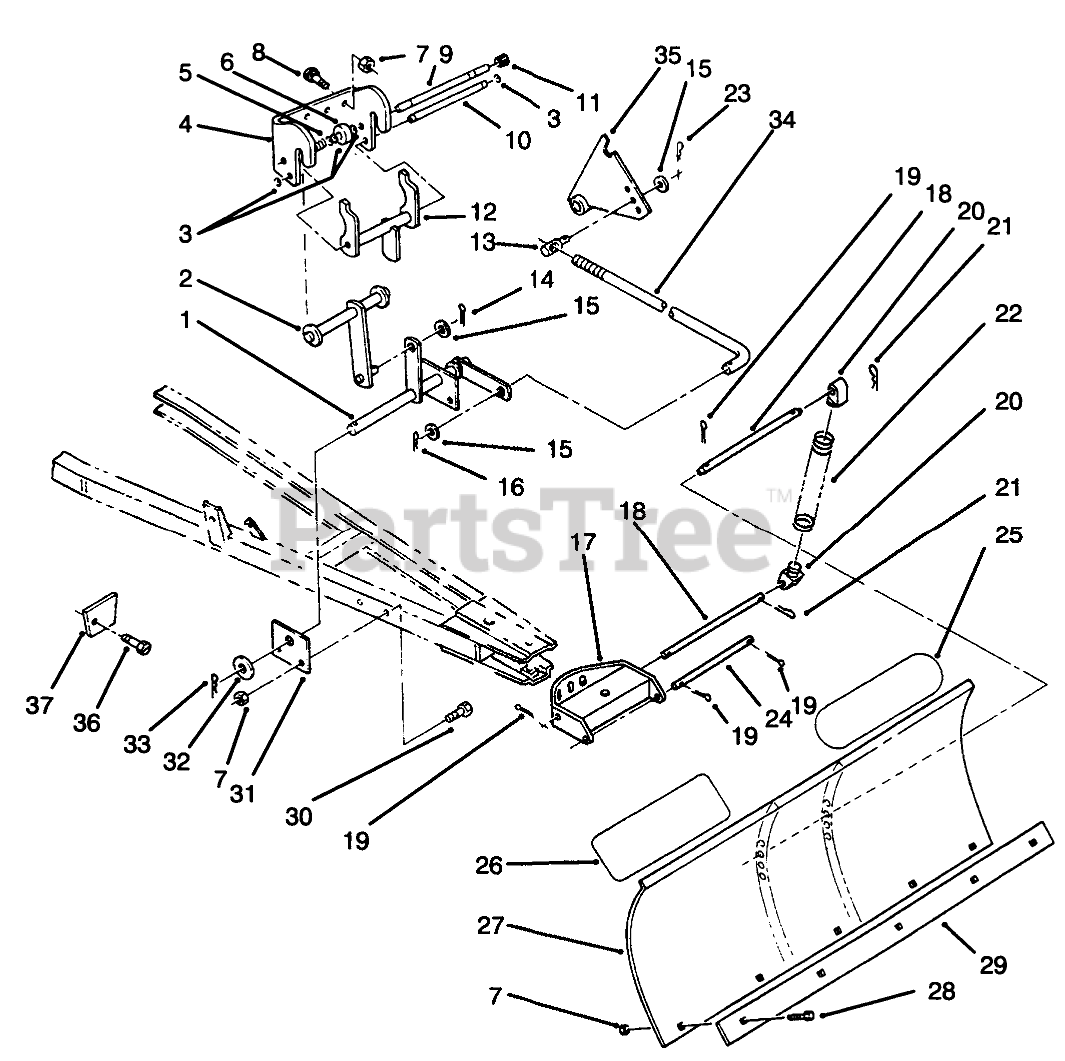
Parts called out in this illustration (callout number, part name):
1	Lift Arm
2	Arm
3	RING-RETAINING
4	Housing-Front Hitch
5	SPRING
7	NUT-LOCK, NI
8	SCREW-CARR
9	ROD-LOCK
10	ROD-LATCH PIVOT
11	CAP-ROD, PLUNGER
12	Assy-Latch
13	STUD-TRUNION
14	PIN-COTTER
15	WASHER-FLAT
16	Hairpin
17	Decal
18	ROD-PIVOT, BLADE
19	PIN-COTTER
20	Lug
21	Hairpin Cotter
22	Spring
23	Hairpin
24	ROD-LOWER
25	DECAL - REAR FRAME
26	DECAL-DANGER
27	Blade & Decal Assembly (Incl. ref. #26)
28	SCREW-CARR
29	Blade Edge Plate
30	SCREW-HH
31	Plate
32	WASHER-FLAT
33	PIN-COTTER
35	Plate
36	HEX WASH HD SCREW
37	Stop-Steering Spindle
